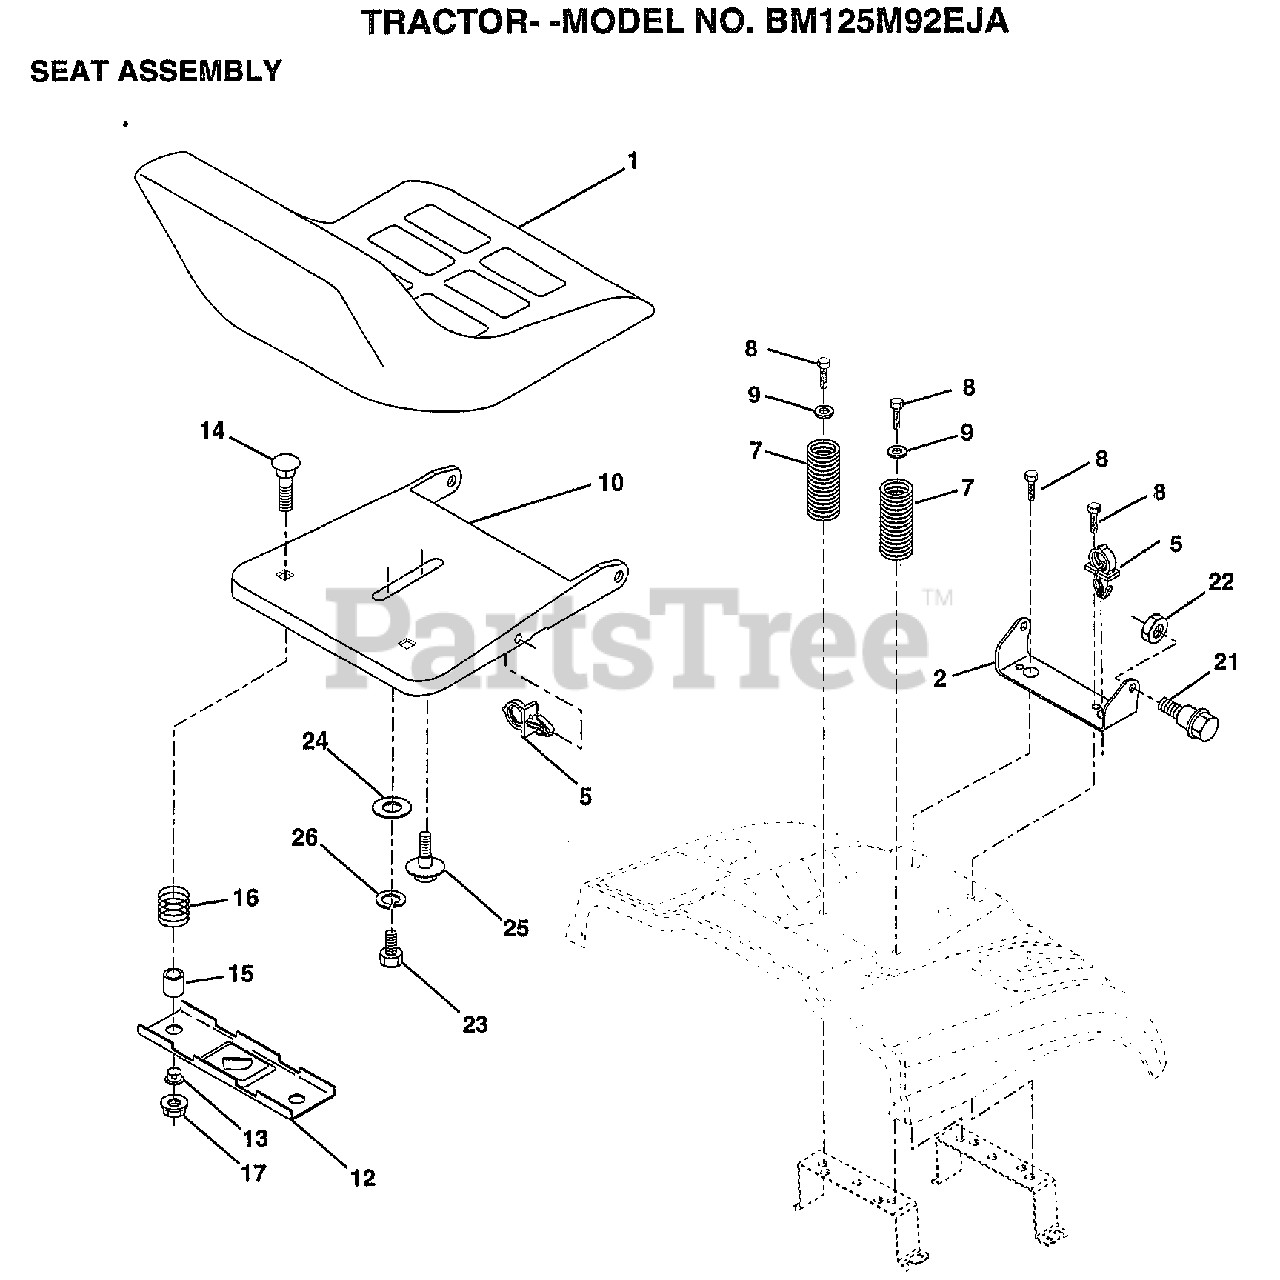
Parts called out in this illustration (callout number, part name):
2	BRACKET PVT SEAT
5	CLIP.PUSH-IN.HING
7	SPRING COMPRESSIO
8	SCREW GTV
9	WASHER
10	PAN-SEAT
12	BRKT SWITCH
13	BUSHING
14	BOLT-RD HD SQ NK
15	SPLIT SPACER
16	SPRING
21	"BOLT,SHOULDER"
22	NUT
23	BOLT
24	WASHER
25	"BOLT,SHOULDER"
26	LOCKWASHER
